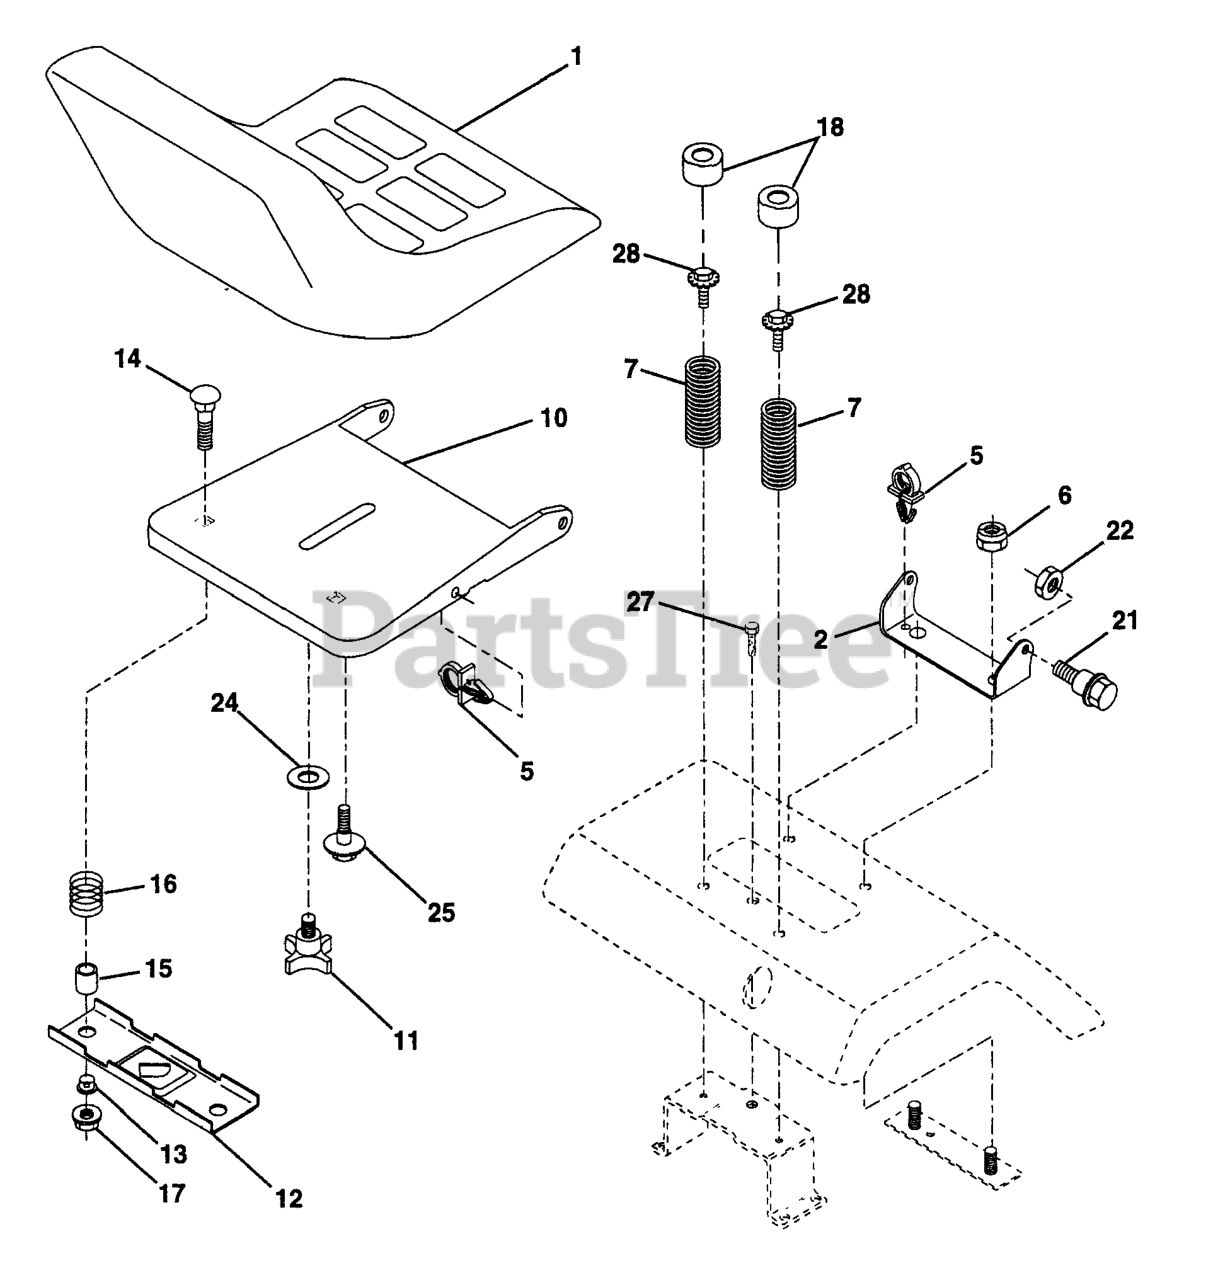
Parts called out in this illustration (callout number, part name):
1	SEAT, GRAY
2	SEAT PIVOT BRKT
6	NUT
7	SPRING COMPRESSION
10	SEAT PAN
11	KNOB 1/2" YT
12	BRKT SWITCH
14	Bolt Rdhd Sht Nk 1/4-20x1-3/8
15	SPACER SPLIT 28X.96
17	NUT T
18	CAP SPRING
21	BOLT SHOULDER 5/16-18
22	NUT.71038.31-18.HEX.NYLOCK
25	BOLT,SHOULD
27	SCREW LT
28	BOLT HEX WASHER HD 5/16-18
